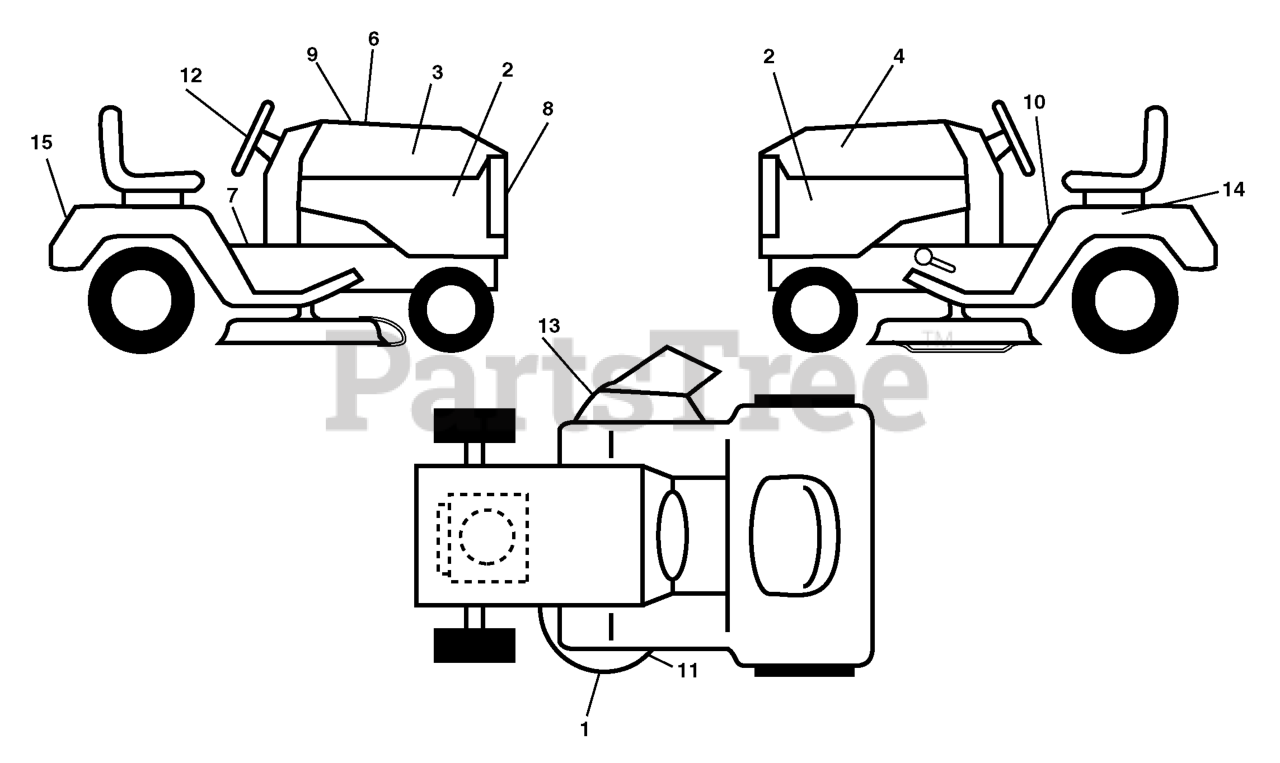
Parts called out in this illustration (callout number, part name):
1	DECAL, MOWER HEAVY DUTY
2	HOOD DECAL, YTH2148
3	DECAL, HOOD RH
4	DECAL, HOOD LH
6	DECAL HOOD CUST. RESP.
9	Decal Replacement
10	DECAL FENDER DANGER
11	DECAL V-BELT SCHEMATIC
12	DECAL.STEERING.HUSQ.BLUE
13	DECAL.WARN.KEEP.HAND.AWAY
14	DECAL BTRY SYMBOLS
15	DECAL.FENDER
